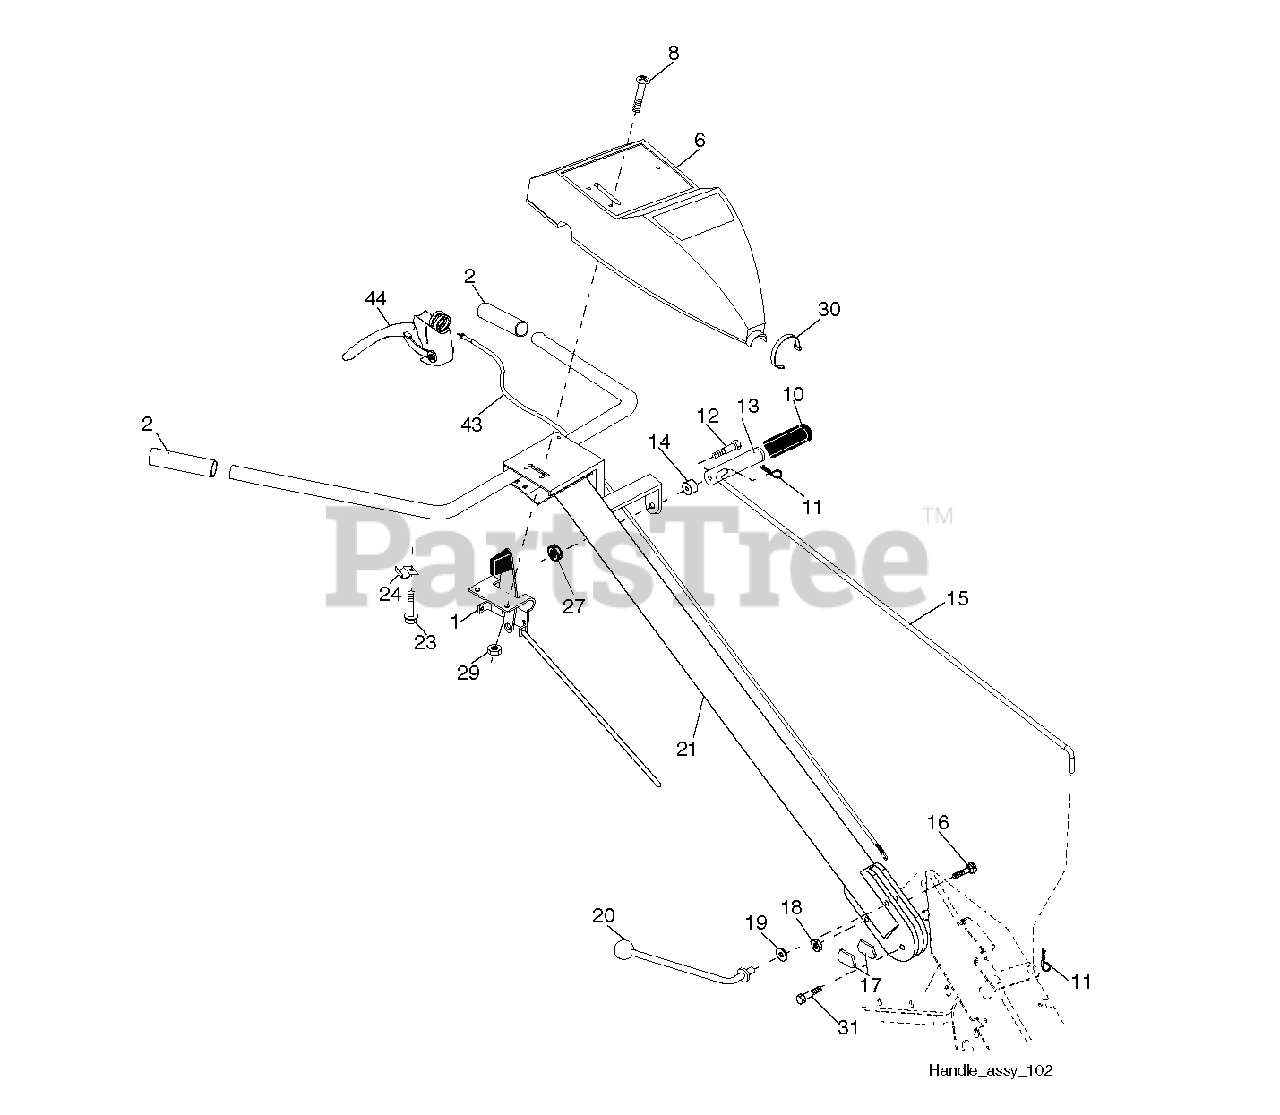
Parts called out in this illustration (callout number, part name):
1	THROTTLE.CONTROL.RT
2	GRIP.1X5.06
8	SCREW.PNHD.10-24
11	RETAINER M
12	SHOULDER BOLT ST
13	HANDLE.SHIFT.TILLER
14	GROMMET.RUBBER.CRT.TILLER
15	SHIFT ROD CRT
18	LOCKNUT
19	WASHER CRT
20	LEVER.LOCK.CRT
23	TAPPING SCREW
24	CONDUIT CLIP T
27	NUT T
29	NUT **
30	TIE CABLE CRT
31	BOLT.PIVOT
